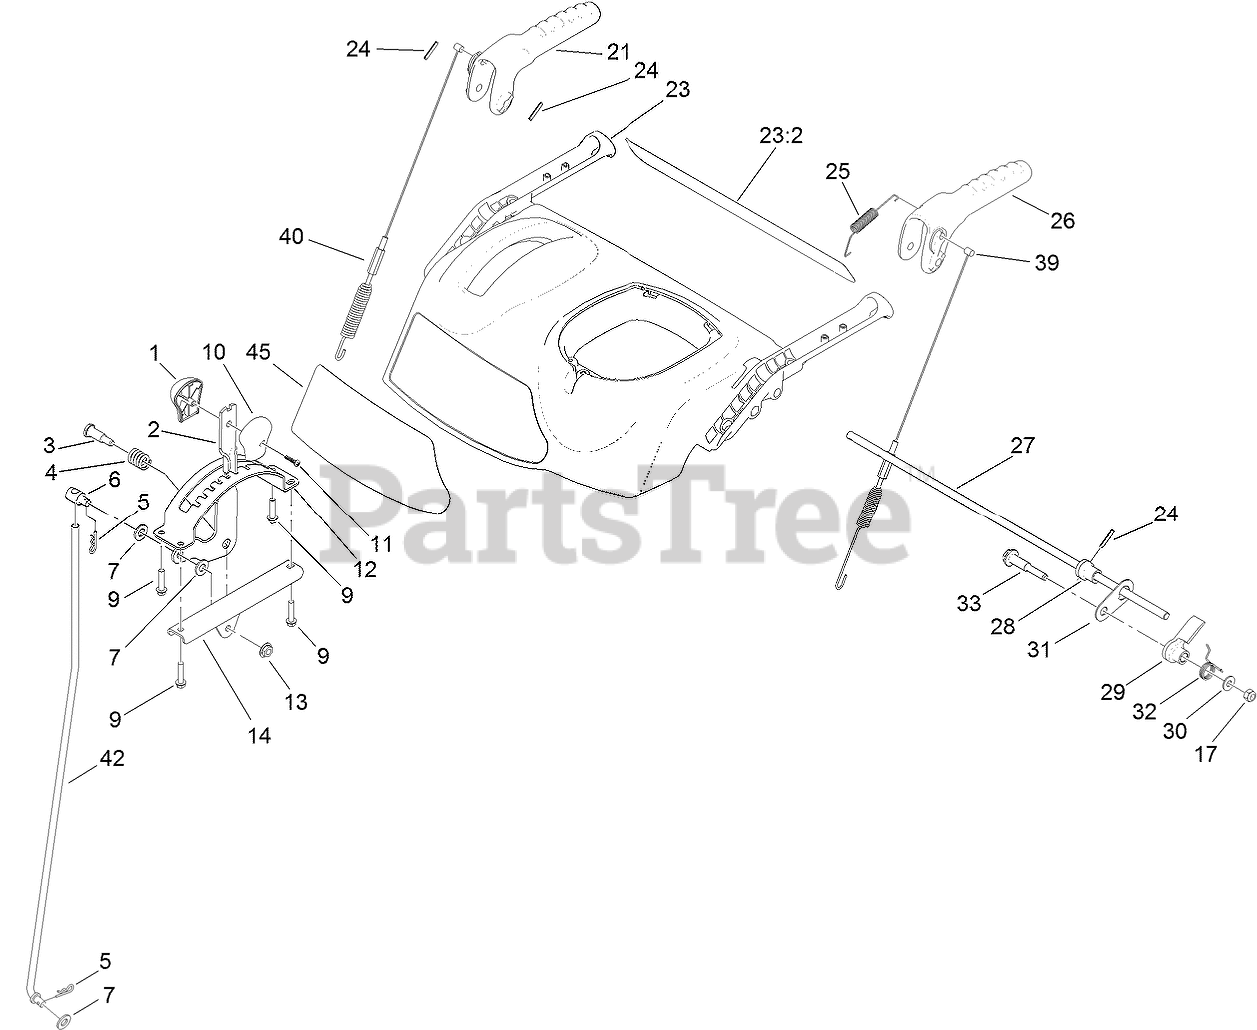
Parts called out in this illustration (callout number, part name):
1	KNOB-SHIFT, RH
2	SELECTOR-SPEED
3	SCREW-SHOULDER
4	SPRING-COMPRESSION
5	PIN-COTTER
6	TRUNNION-ROD
7	WASHER-FLAT
9	SCREW-PLASTITE
10	KNOB-SHIFT, LH
11	SCREW-PPH
12	GUIDE-SELECTOR, SPEED
13	NUT-HF
14	MOUNT-SELECTOR, SPEED
17	NUT-LOCK, NI
21	LEVER-AUGER
23	CONTROL PANEL ASM
23:2	DECAL-PANEL, CONTROL
24	PIN-SPRING
25	SPRING-TENSION
26	LEVER-TRACTION
27	ROD-LOCKOUT
28	CAM-LOCKOUT
29	LATCH-LOCKOUT
30	WASHER-FLAT
31	LINK-LOCKOUT
32	SPRING-TORSION
33	SCREW-SHOULDER
39	CABLE-TRACTION
40	CABLE-AUGER
42	ROD-SHIFT
